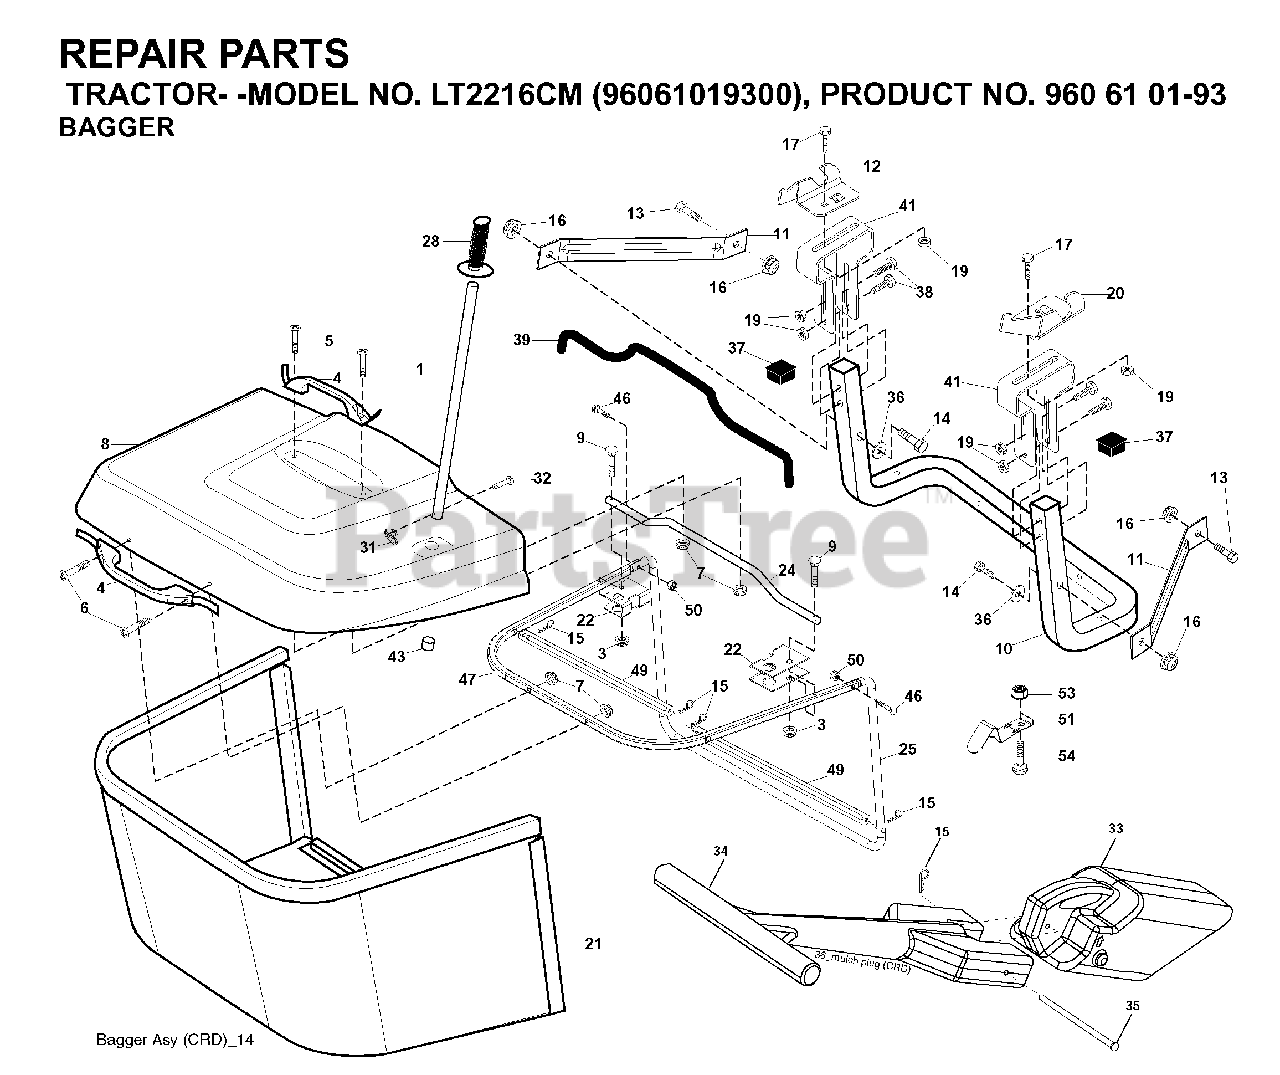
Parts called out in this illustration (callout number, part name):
1	TUBE HANDLE
3	NUT T
5	SCREW.PAN.HEAD
11	BRACKET
14	BOLT-HEX EAK
15	RETAINER-SPRNG RB
16	NUT LOCK FLG 3/8-16 UNC
17	BOLT
19	NUT LOCK HEX FLANGE 5/16-18
20	BRKT.PIVOT.RH.CRD
21	BAGGER.ASM.CRD.2007
22	BRACKET
24	TUBE
28	GRIP.HANDLE.BLACK
31	RETAINER CLIP
32	RIVET,DRILLED
33	PLUG
35	PIN
38	BOLT.5/16-18X2.5
41	BRKT, BAGGER
43	PLUG, TUBING END
46	BOLT.CARRIAGE.5/16-18
50	NUT.71038.31-18.HEX.NYLOCK
53	NUT
54	BOLT
